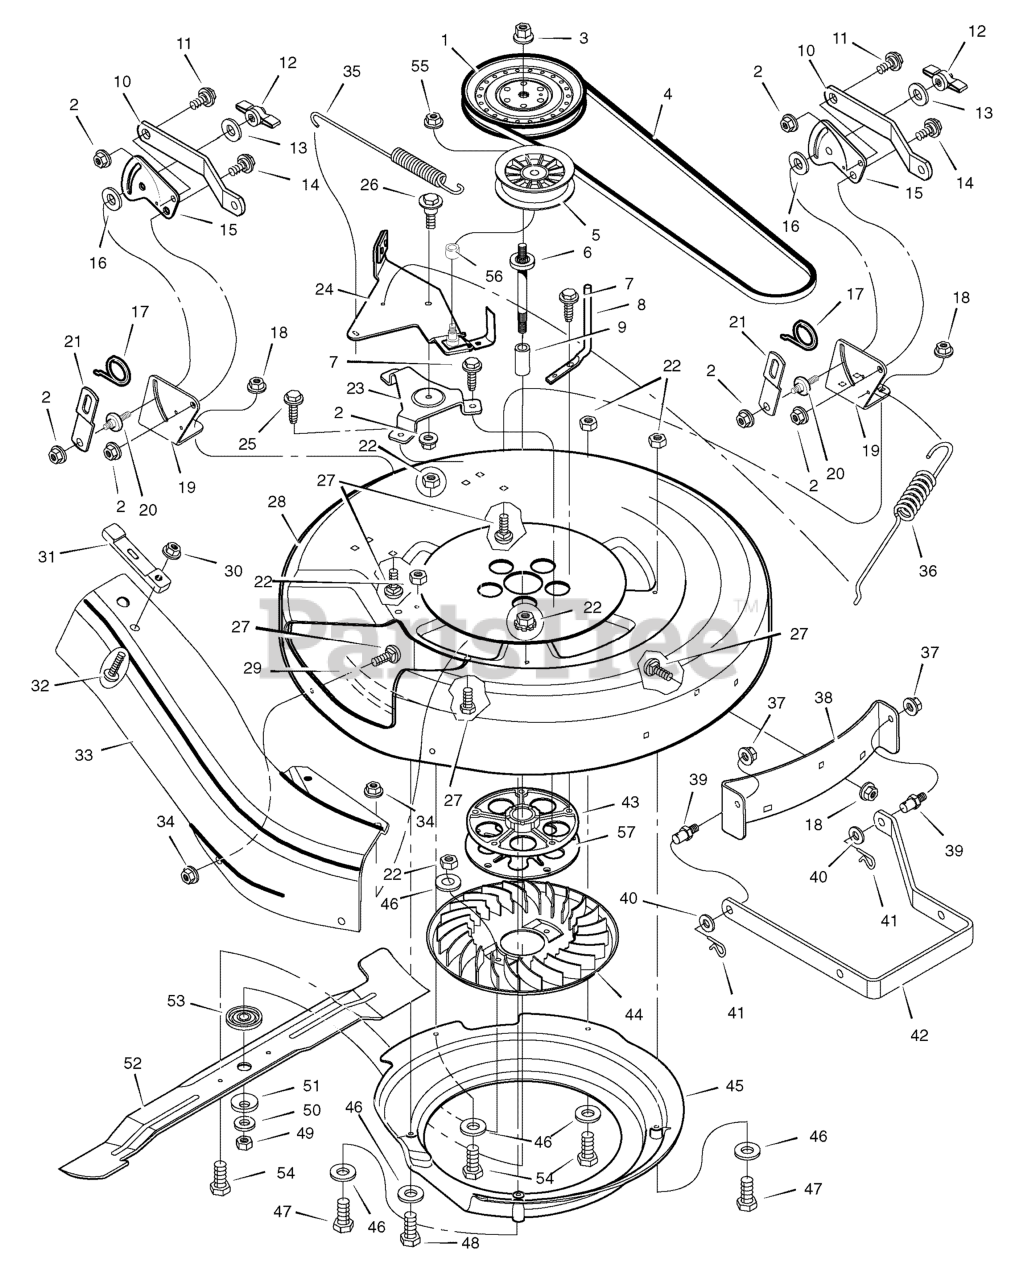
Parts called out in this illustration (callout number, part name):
2	NUT, Flange
4	BELT, Blade
5	PULLEY, Idler
8	GUIDE, Belt
10	BRACKET, Rear Suspension
11	BOLT, Shoulder
14	BOLT, Shoulder
15	PLATE, Suspension
16	PAD, Friction
18	NUT, Flange
19	BRACKET, Rear Deck
20	PIN, Hanger
21	LINK, Lift
23	BRACKET, Idler Arm
24	ASSEMBLY, Idler Arm & Pad
26	BOLT, Shoulder
27	BOLT, Carriage
28	HOUSING, Blade
29	BAFFLE, Deck, RH
30	NUT, Flange
31	STRAP, Rubber
35	SPRING, PTO
36	SPRING, Extension
37	NUT, Flange
38	BRACKET, Front Deck
39	PIN, Threaded Shoulder
41	PIN, Hair
42	HANGER, Front
43	HOUSING, Jackshaft
44	FAN, Assist
45	HOUSING, Fan
51	WASHER, Belleville
53	ADAPTER, Blade
55	NUT, Flange
57	PLATE, Jackshaft Support
